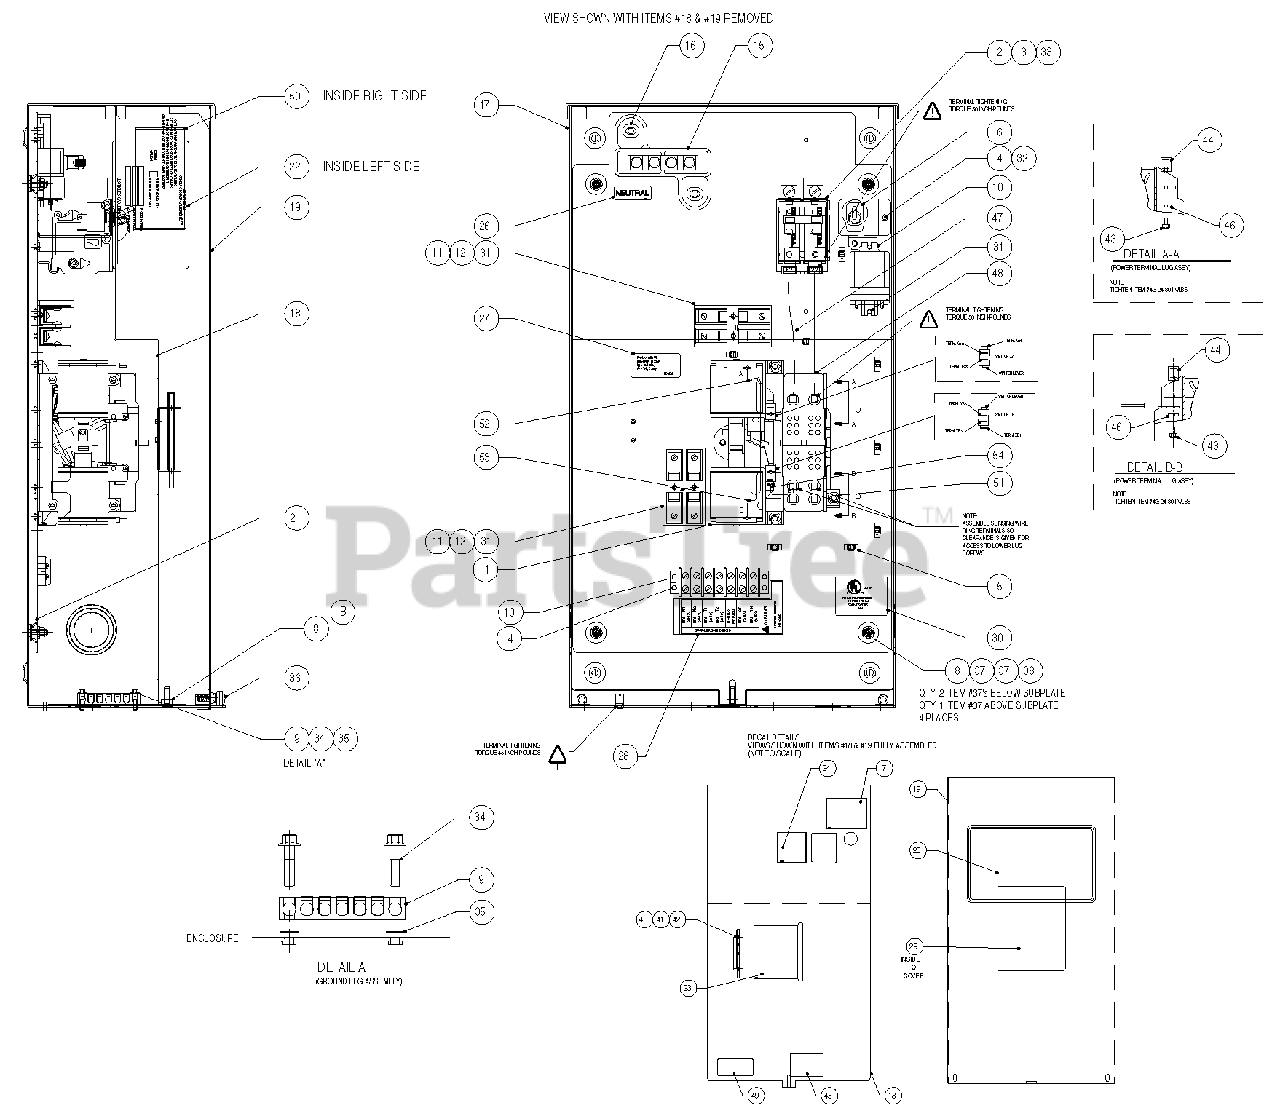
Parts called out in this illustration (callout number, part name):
1	TRANSFER SW-HSB 100A 2P 250V
2	CB 0100A 2P 240V S BQ2 LB
3	BRKT CB MTG BACK
4	BRACKET, DISCONNECT SWITCH 100A
5	HOLDER, CABLE TIE
6	SWITCH TOG SPST 15A @ 125V
7	DECAL SERVICE DISCONNECT SWITCH
8	NUT HEX M6 X 1.0 G8 YEL CHR
9	GROUND BAR (5)4-14 AWG CONN
10	RELAY PNL 12VDC DPDT 10A@240VA
11	FUSEBLOCK 30A 600V 2POS W/SQ
12	FUSE 5A X BUSS
13	BLOCK TERM 20A 7 X 6 X 1100V
14	RIVET POP .156 X .675 AL
15	ASS'Y-NTRL BL 150-200A
16	SCREW HHTT M6-1.0 X 12 ZINC
17	WELDMENT TRANSFER SWITCH BOX
18	COVER INSIDE XFER SWITCH BOX
19	COVER TRANSFER SWITCH BOX
20	DECALTRANSFER SWITCH
21	SUBPLT XFER SW HSB
22	DECAL SWITCH RATING
23	DECAL WARN MANUAL OPER HANDLE
24	DECAL SERVICE DISCONNECT
26	DECAL NEUTRAL
27	DECAL FUSE REPLACEMENT
28	DECAL TERMINAL STRIP
29	DECAL TEST SEQ. 2P TS HS 3R
30	DECAL-UL LIST HSB
31	SCREW HHTT M4-0.7 X 8 BP
32	SCREW HHTT M5-0.8 X 10 BP
33	SCREW HHTT M5-0.8 X 8 BP
34	SCREW HHTT M4-0.7 X 16 BP
35	WASHER SHAKEPROOF EXT #8 STEEL
36	SCREW THUMB 1/4-20 X 1/2 W/SHLD
37	WASHER FLAT 1/4-M6 ZINC
38	WASHER LOCK M6-1/4
40	BRACKET ARM EXTENDER
41	SCREW HWHS #6-25 X 3/8 ZNC
42	ARM EXTENDER PIN
43	SCREW PPHM #10-32 X 3/8
44	LUG SLDLSS 1/0-#14X9/16 AL/CU
45	DECAL TERMINAL SHOCK HAZARD
46	WASHER LOCK #10
47	WIRE ASSY 2AWG 100A 2-P T/S N1A
48	WIRE ASSY 2AWG 100A 2-P T/S N2A
49	DECAL LIVE-CIRCUIT
50	DECAL XFER SWITCH DATA SE 100A
51	SCREW HHTT M5-0.8 X 16
52	WIRE - A
53	WIRE - B
54	WIRE - E1
